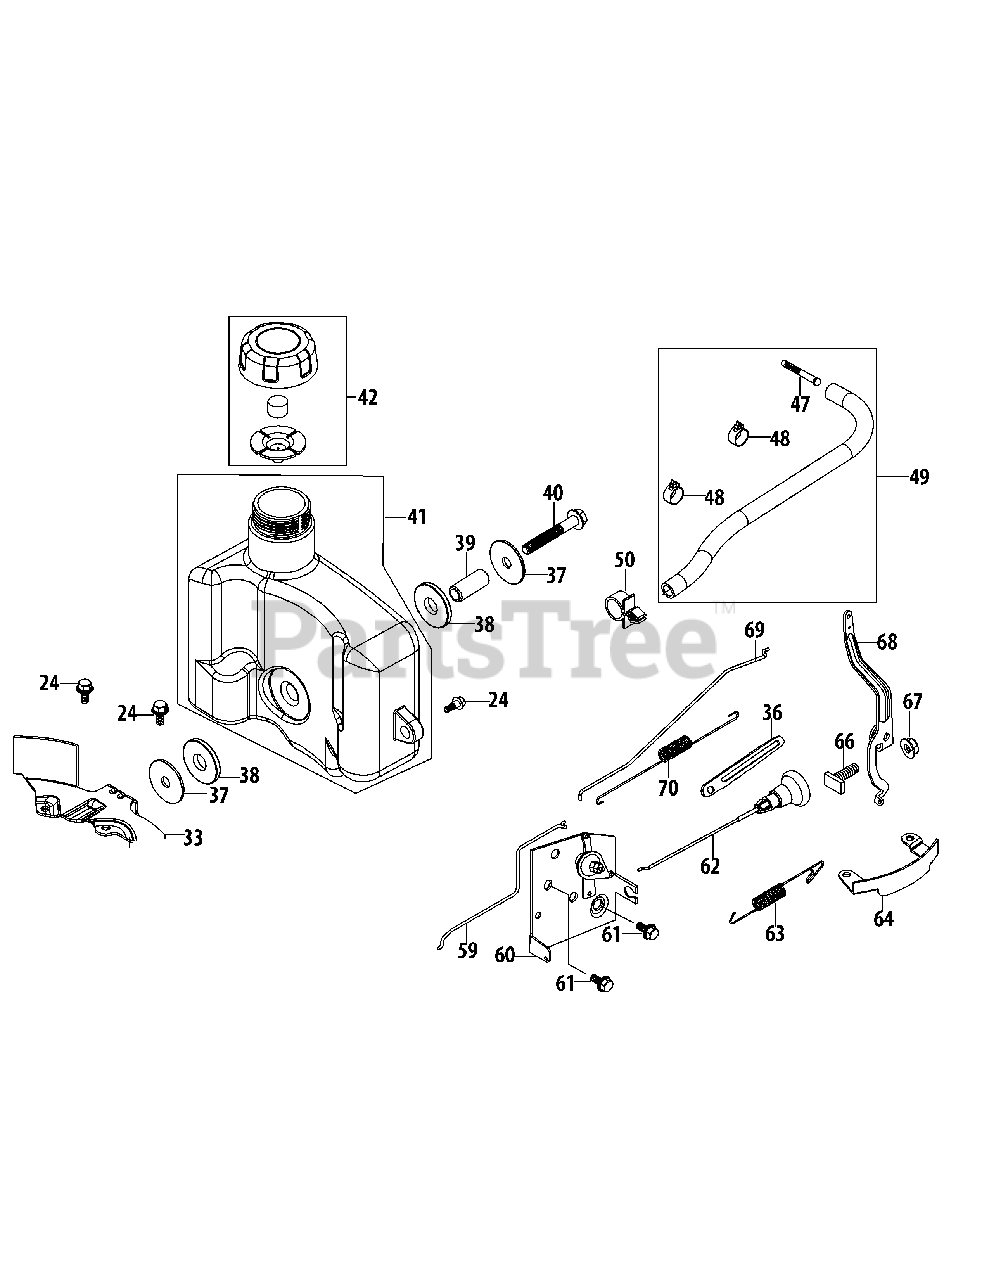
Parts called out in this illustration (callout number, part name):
24	Bolt M6X14
33	Fuel Tank Bottom Bracket
36	Flexible Clamp
37	Fuel Tank Washer
38	Rubber Bushing
39	Fuel Tank Bushing
40	Bolt M8X50
41	Fuel Tank Assembly
42	Fuel Cap Assembly
47	Fuel Filter
48	Fuel Hose Clamp
49	Fuel Line Kit
50	Plastic Support Clamp
59	Choke Linkage
60	Component Bracket
61	Bolt M6X12
62	Choke Control
63	Governor Spring
64	Governor Arm Guard
66	Governor Arm Bolt
67	Governor Arm Nut M6
68	Governor Arm
69	Throttle Linkage Rod
70	Throttle Linkage Spring
